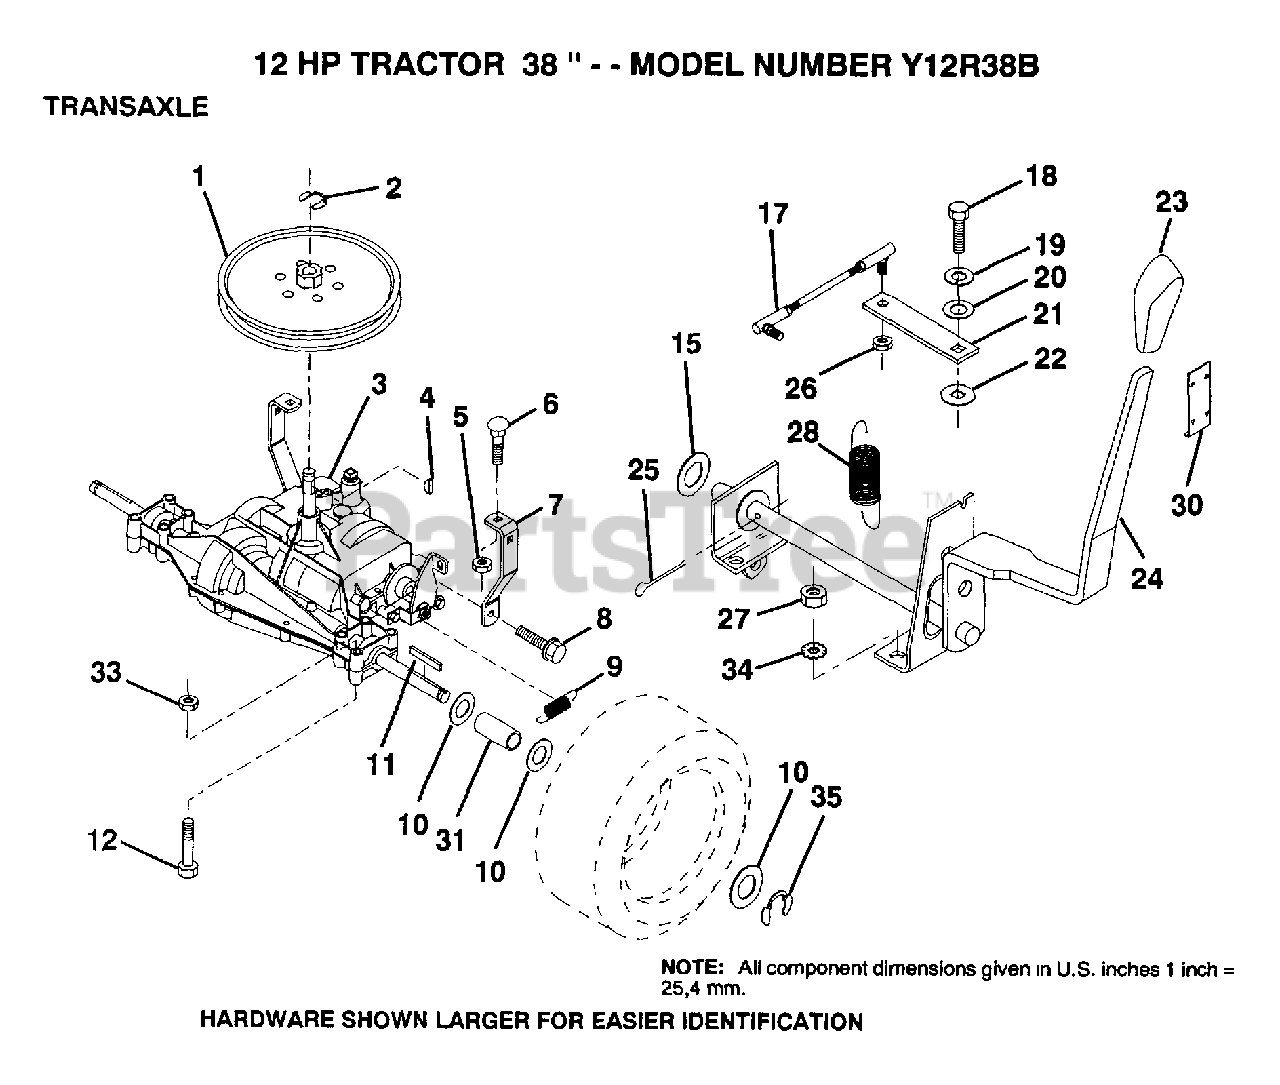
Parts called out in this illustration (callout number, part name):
1	PULLEY
3	TRANSAXLE.6SP.D
6	BOLT
7	"STRAP,TORQUE"
8	SCREW
10	WASHER
11	SQUARE KEY
12	BOLT
17	"LINK,SHIFT"
19	LOCKWASHER
20	WASHER LT
21	"ARM,SHIFT"
22	WASH-SHFT PLT LT
23	"KNOB,SHT CONTROL"
25	PIN COTTER 1/8
26	NUT.LOCK.5/16-24
28	"SPRING,EXT"
30	KNOB RETAINER
31	SPACER
34	LOCKWASHER.5/16.E
35	E-RING LT
